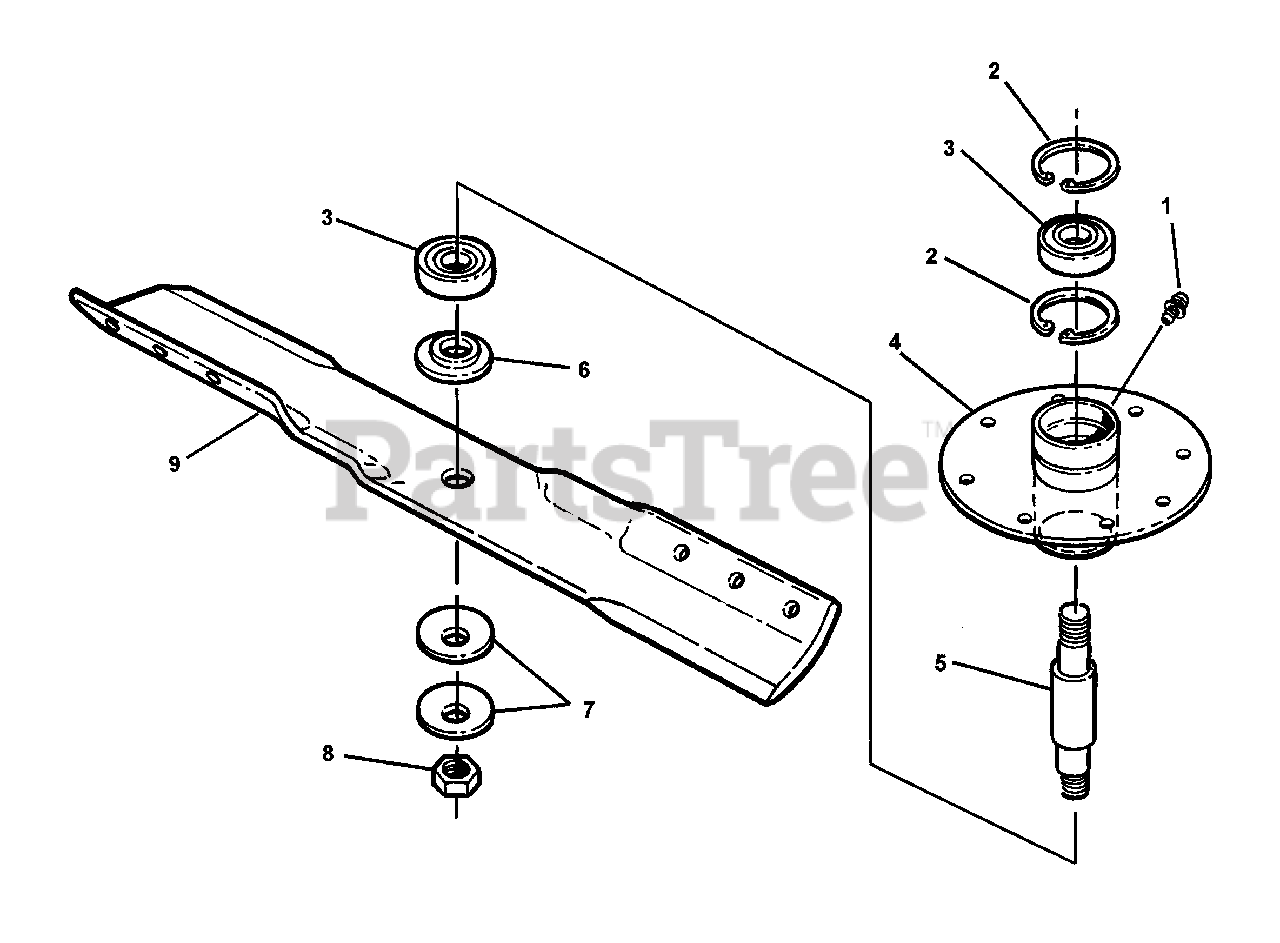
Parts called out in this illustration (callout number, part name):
1	FITTING, Lube (Press fit for .187 hole-no ball)
2	RING, Retaining
3	BEARING, Spindle
4	HOUSING, Spindle
5	SHAFT, Spindle
6	WASHER, Spindle
7	WASHER, Belleville, 19/32" I.D. x 1-3/4" O.D.
8	NUT, 9/16-18 Hex Jam
9	BLADE, 19"
